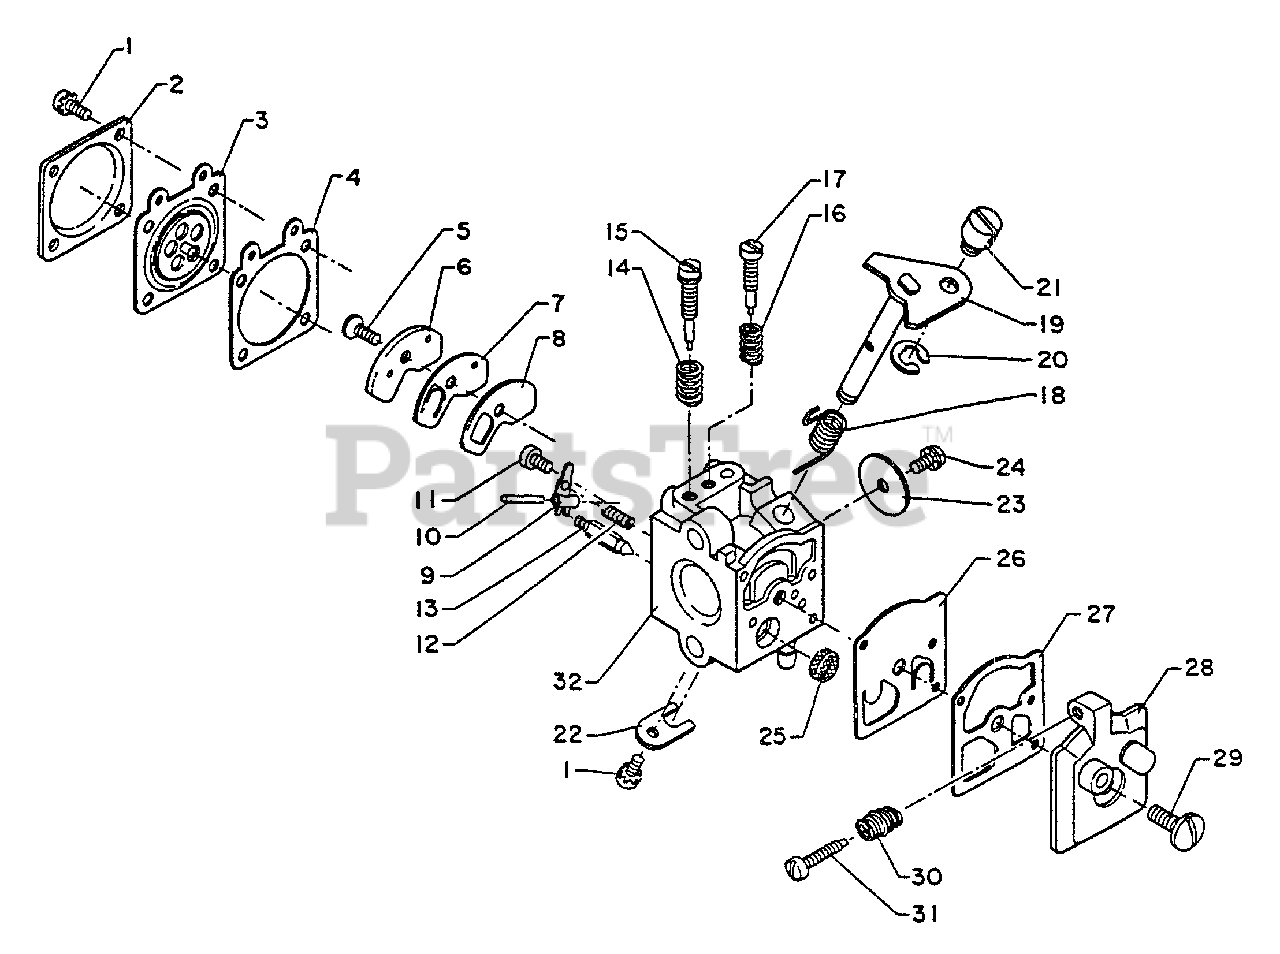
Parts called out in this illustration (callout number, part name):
1	REPAIR KIT
2	COVER, METERING
3	REPAIR KIT
4	REPAIR KIT
5	REPAIR KIT
6	PLATE, CIRCUIT
7	REPAIR KIT
8	REPAIR KIT
9	REPAIR KIT
10	REPAIR KIT
11	REPAIR KIT
12	REPAIR KIT
13	REPAIR KIT
14	REPAIR KIT
15	NEEDLE - HIGH SPEED
16	REPAIR KIT
17	NEEDLE - LOW SPEED
18	SPRING, THROTTLE RETURN
19	SHAFT, THROTTLE
20	RING, RETAINING
22	CLIP, THROTTLE SHAFT
23	VALVE, THROTTLE
25	REPAIR KIT
26	REPAIR KIT
27	REPAIR KIT
28	COVER, PUMP
29	SCREW, PUMP COVER
30	SPRING, IDLE ADJUST
31	SCREW, IDLE ADJUST
32	BODY, CARBURETOR
